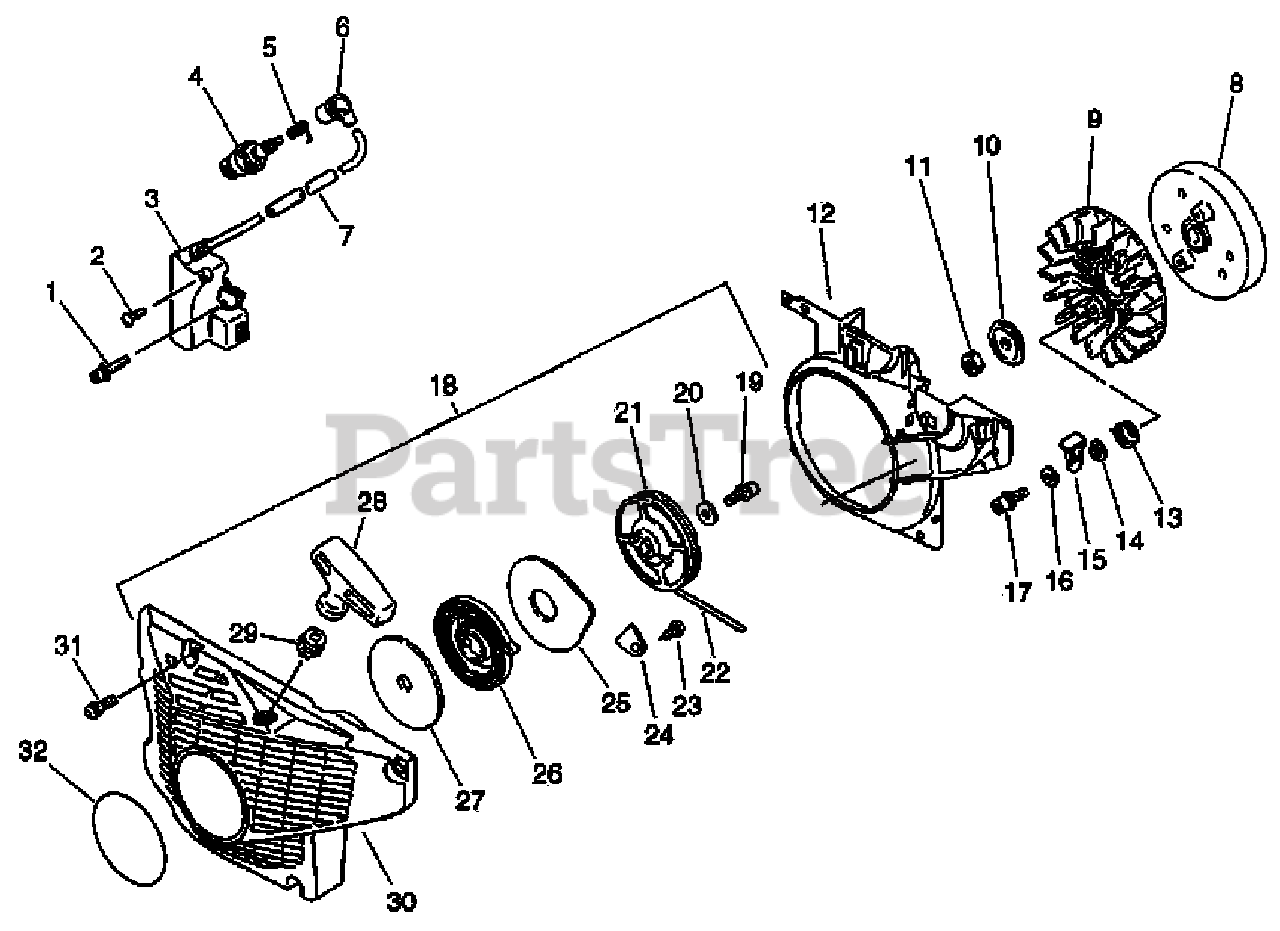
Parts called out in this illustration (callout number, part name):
1	SCREW - 4X20
2	SCREW - 4X8
3	COIL, IGNITION
4	SPARK PLUG -- BPMR-7A
5	TERMINAL, SPARK PLUG CAP
6	CAP, SPARK PLUG
8	FLYWHEEL
10	WASHER - CUP
12	COVER, FAN
13	SPRING, RETURN
14	SPACER, PAWL
15	PAWL, STARTER
16	WASHER - 5
17	SCREW - 5X20
18	STARTER ASSY
19	SCREW - 5X14
20	WASHER - 5
21	REEL, ROPE
22	ROPE, STARTER - 4X900
23	SCREW - 4X8
24	RETAINER, BRAKE BAND
25	PLATE, STARTER
26	SPRING, REWIND
27	PLATE, STARTER
28	GRIP, STARTER
29	GUIDE, ROPE
30	CASE, STARTER
31	SCREW - 5X20
32	LABEL - ECHO
